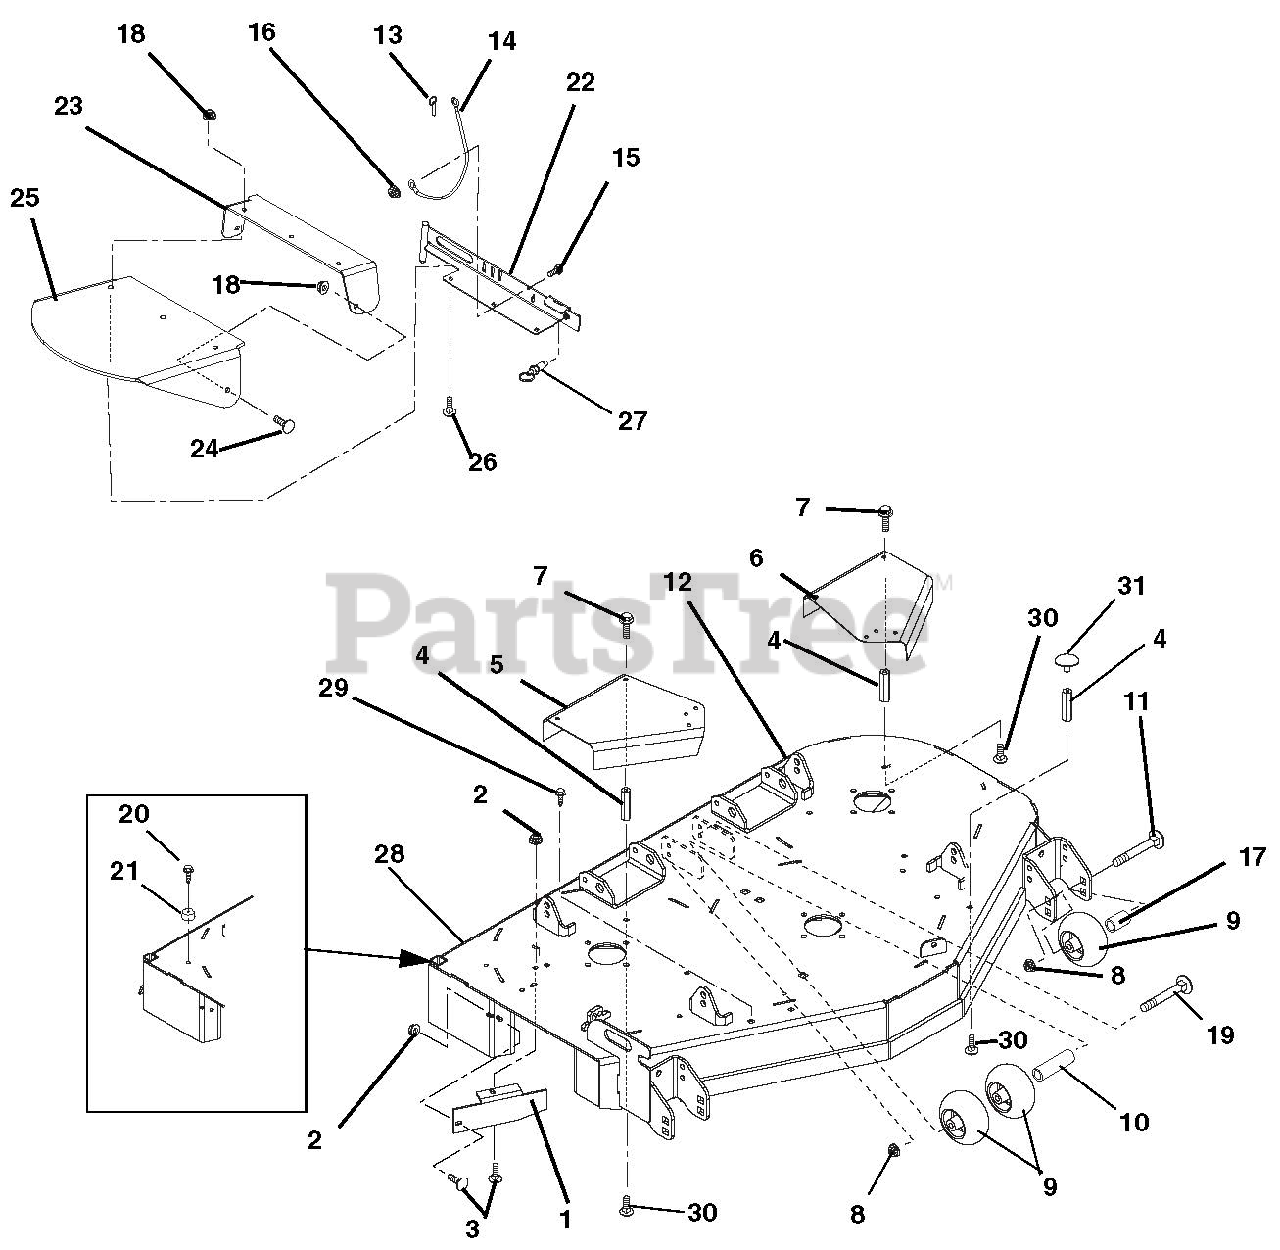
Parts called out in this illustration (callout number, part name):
1	44 in. & 48 in. Rear Discharge Baffle
2	Nut, .31-18 Nyloc Flange
3	Bolt, Round Head Square Neck .31-18 x 1.00 Grade 5
4	Nut, Coupling .31-18 x 3.00
5	Right Hand Spindle Guard
6	44 in., 48 in., & 52 in. Left Hand Spindle Guard
7	Bolt, SEMS .31-18 x .62
8	Nut .50-13 Nyloc Flange
9	Anti-Scalp Wheel
11	Bolt-Round Head Square Neck .50-13X5.00
12	44 in. Side Discharge Mower Deck
13	Pin, Spring Ball .375 OD x 1.50
14	Cable, 5-in.
15	Bolt, Hex .25-20 x .75 Grade 5
16	Nut, Locking Top Flange .25-20
17	Spacer, .510 x .625 x 3.35
18	Nut, .38-16 Nyloc Flange
19	Bolt, Round Head Square Neck .50-13 x 8.50
20	Screw, Tapping .31-18 x .75 Hex Washer Head Thread
21	Bumper, Recessed 1.50 x .63 , .31 Thru Hole
22	44 in. & 48 in. Discharge Chute Mounting Weldment
23	Rubber Discharge Chute Support
24	Bolt, Round Head Square Neck .38-16 x 1.00 Grade 5
25	Chute, Rubber Discharge
26	Bolt, Round Head Square Neck .38-16 x 1.25 Grade 5
27	Pin, Pull
28	Deck, 44" Side Discharge
29	Screw, Tapping .38-16 x .50
30	Bolt, Round Head Square Neck .31-18 x .75 Loctite
31	Bumper, Rubber
